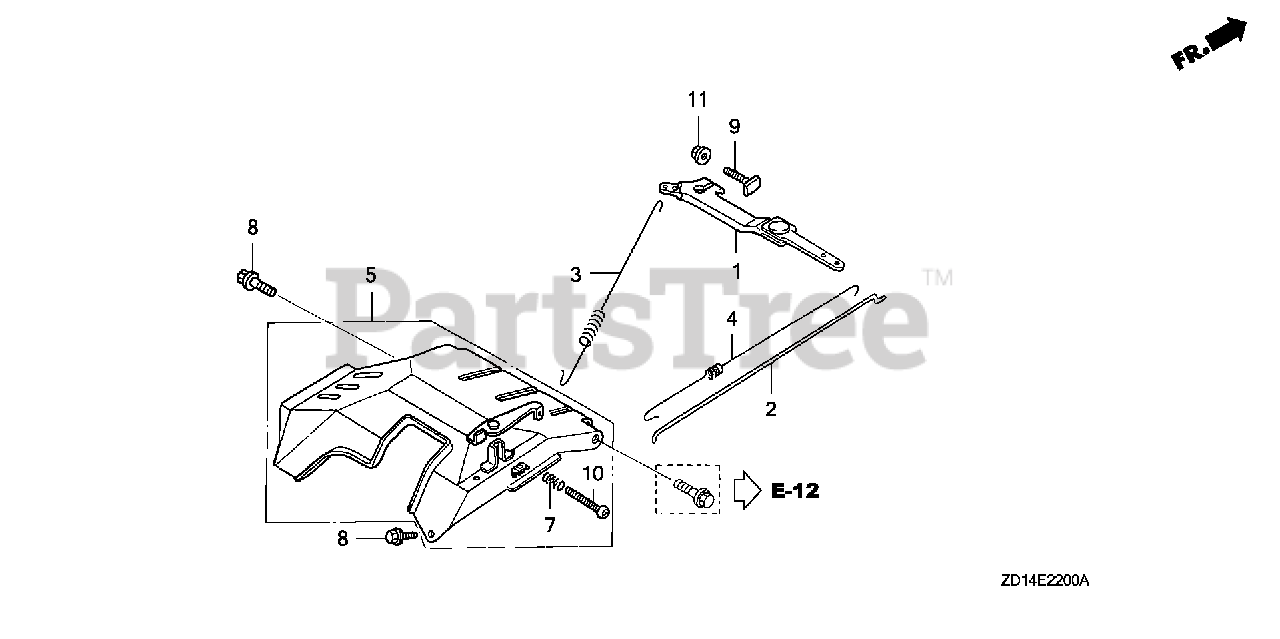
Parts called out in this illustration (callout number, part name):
1	ARM, GOVERNOR
2	ROD, GOVERNOR
3	SPRING, GOVERNOR
4	SPRING, THROTTLE RETURN
5	CONTROL ASSY.
7	SPRING, CONTROL ADJUSTING
8	BOLT, FLANGE (6X12) (CT200)
9	BOLT, GOVERNOR ARM
10	SCREW, PAN (5X35)
11	NUT, FLANGE (6MM)
